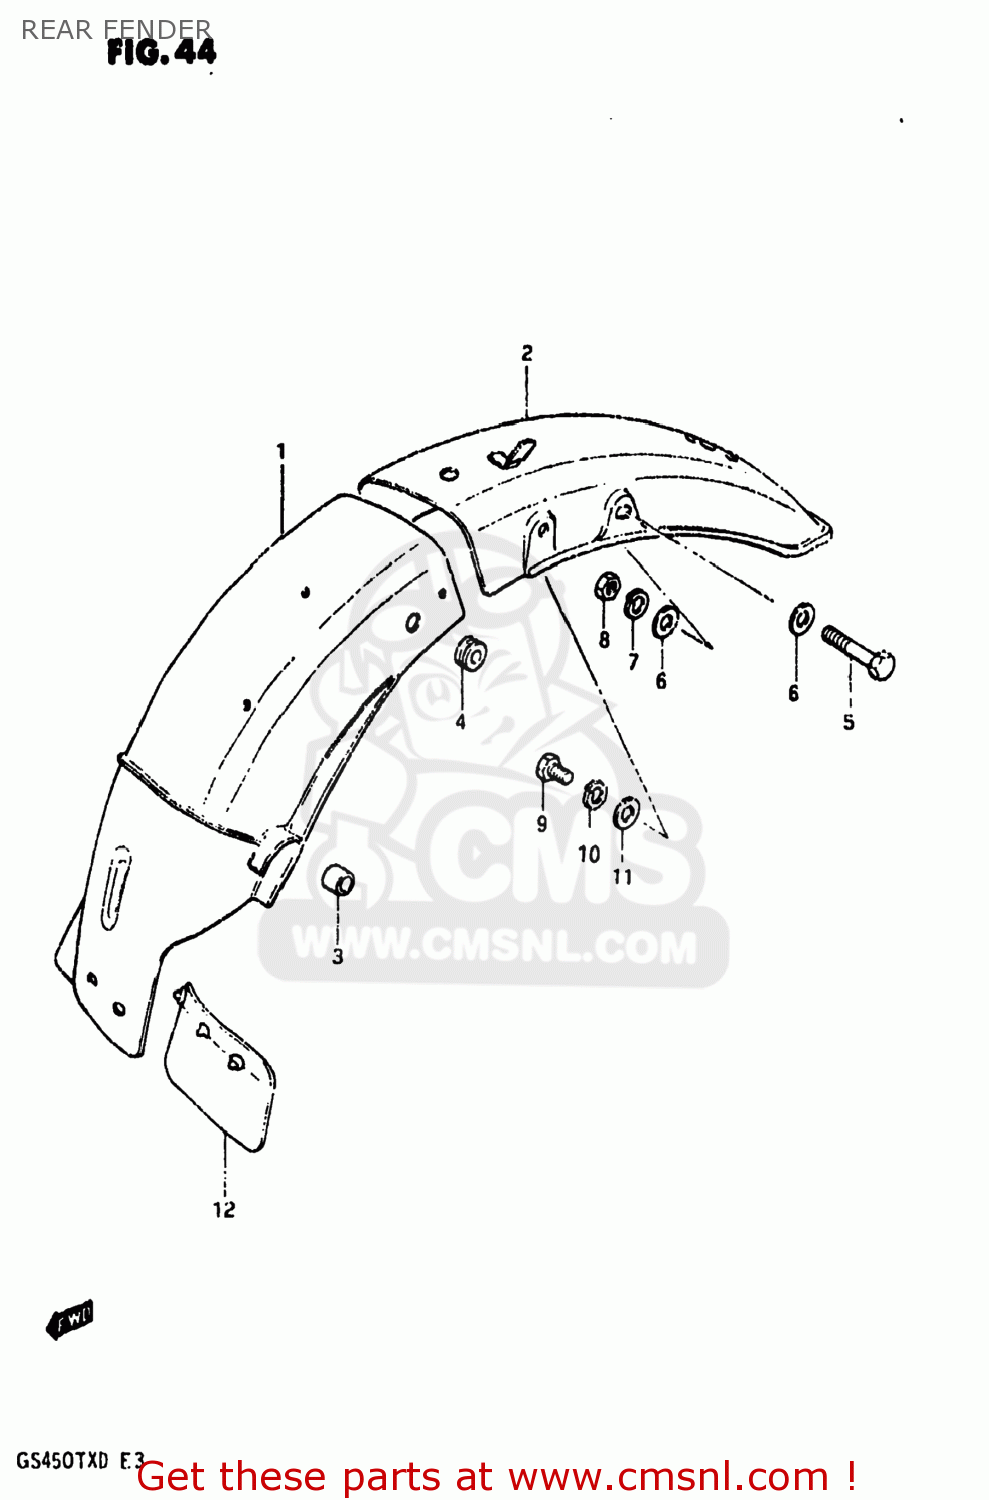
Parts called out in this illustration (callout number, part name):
1	FENDER,REAR
2	FENDER,REAR
3	CUSHION
4	CUSHION
5	BOLT
6	WASHER
7	LOCK WASHER
8	NUT
9	BOLT 8X12
10	LOCK WASHER
11	WASHER
12	GUIDE,RR FENDER MUD
